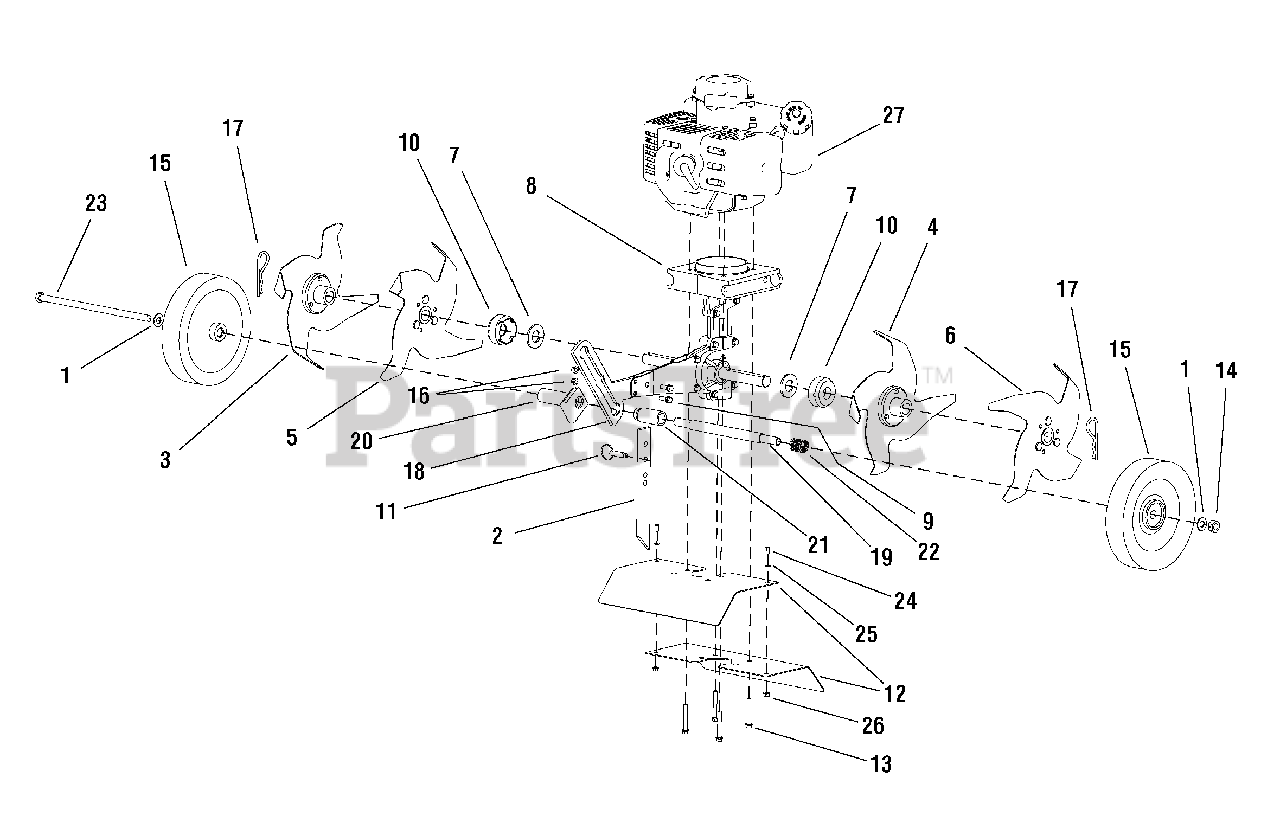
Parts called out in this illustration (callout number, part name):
1	WASHER, 10mm Narrow Flat
2	DRAG BAR
3	TINE D, Left Outside
4	TINE B, Right Inside
5	TINE C, Left Inside
6	TINE A, Right Outside
7	WASHER, Fiber
8	TRANSMISSION ASSEMBLY
9	BOLT, Hex Head Flanged, M6 x 1 x 15mm
10	DUST CAP
11	PIN, Detent, 5/16 x 1-1/2
12	SHIELD, Tine
13	BOLT, Hex Head Flanged, M6 x 1 x 42mm
14	NUT, Centerlock, Hex Head, M10 x 1-1/2
15	WHEEL
16	NUT, Hex Head Flange, M6 x 1
17	COTTER PIN, Hair, 5/8-3/4
18	WHEEL HOLDER
19	WHEEL TUBE
20	GUIDE, Wheel Tube
21	TUBE, Wheel Lock
22	SPRING, Wheel Lock
23	BOLT, Hex Head, M10 x 1-1/2 x 225mm
24	BOLT, Phillips Pan Head, M4 x 0.7 x 10mm
25	WASHER, Flat, M4
26	NUT, Hex Head Flanged, M4 x 0.7
27	* Engine, 43CC CAT Convert
27	* Engine, 43CC CAT Convert, Electric Start
